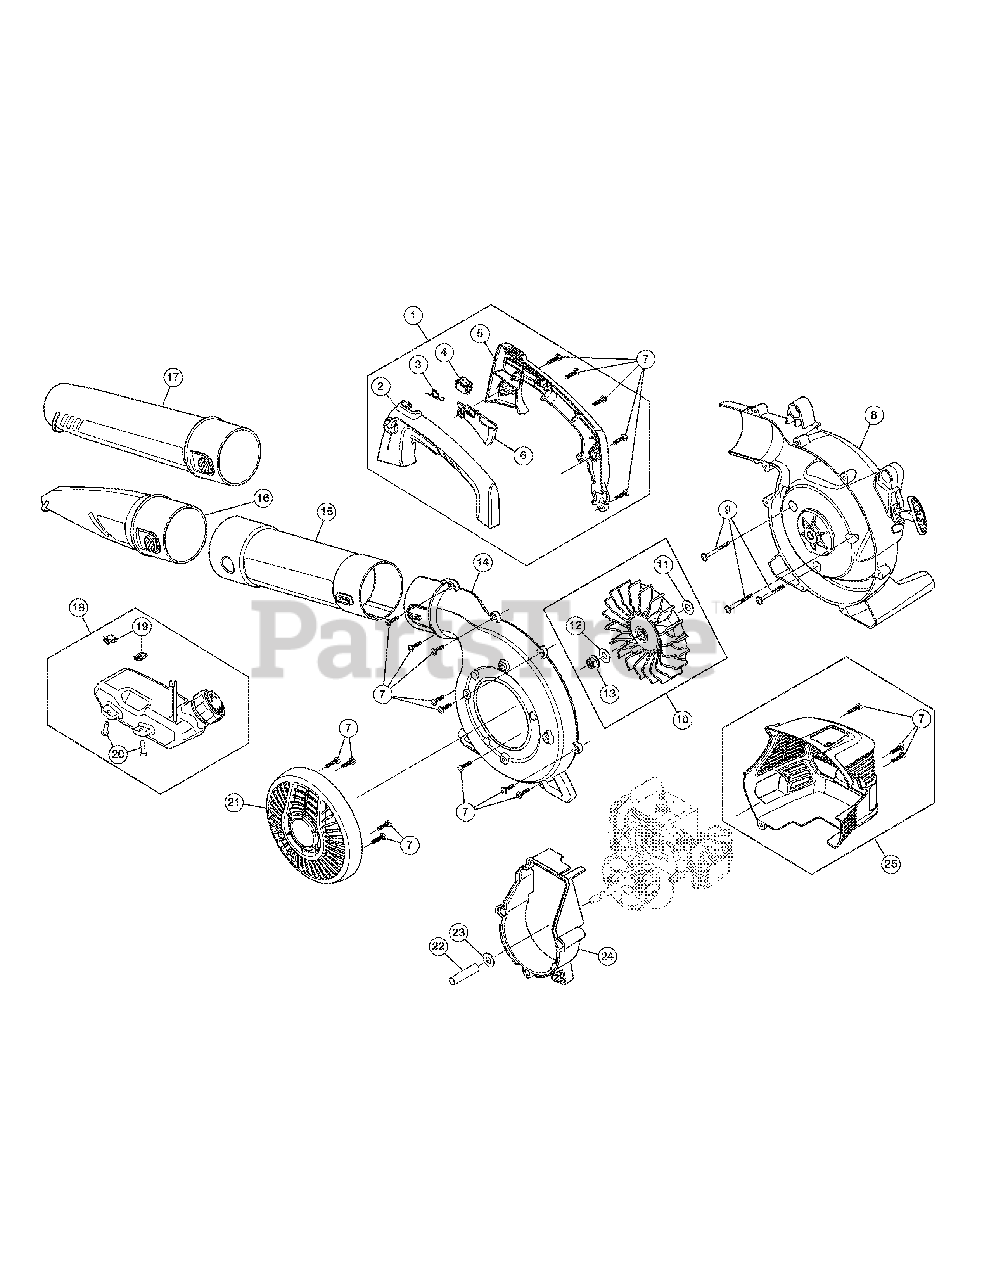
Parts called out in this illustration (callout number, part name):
1	Handle Assembly
2	Handle (LH)
3	Trigger Spring
4	On/Off Switch
5	Handle (RH)
6	Throttle Trigger
8	Impeller Housing Assembly (RH) (Incl. 9)
10	Impeller Assembly
11	Washer
12	Lock Washer
14	Impeller Housing Assembly (LH) (Incl. 7)
15	Upper Blower Tube
16	Blower Nozzle
17	Lower Blower Tube
18	Fuel Tank Assembly
19	U-Shaped Nut
21	Intake Cover (Incl. 7)
22	Shaft Spacer
23	Washer
24	Engine Adapter (Incl. 9)
25	Engine Cover Housing (Incl. 7)
